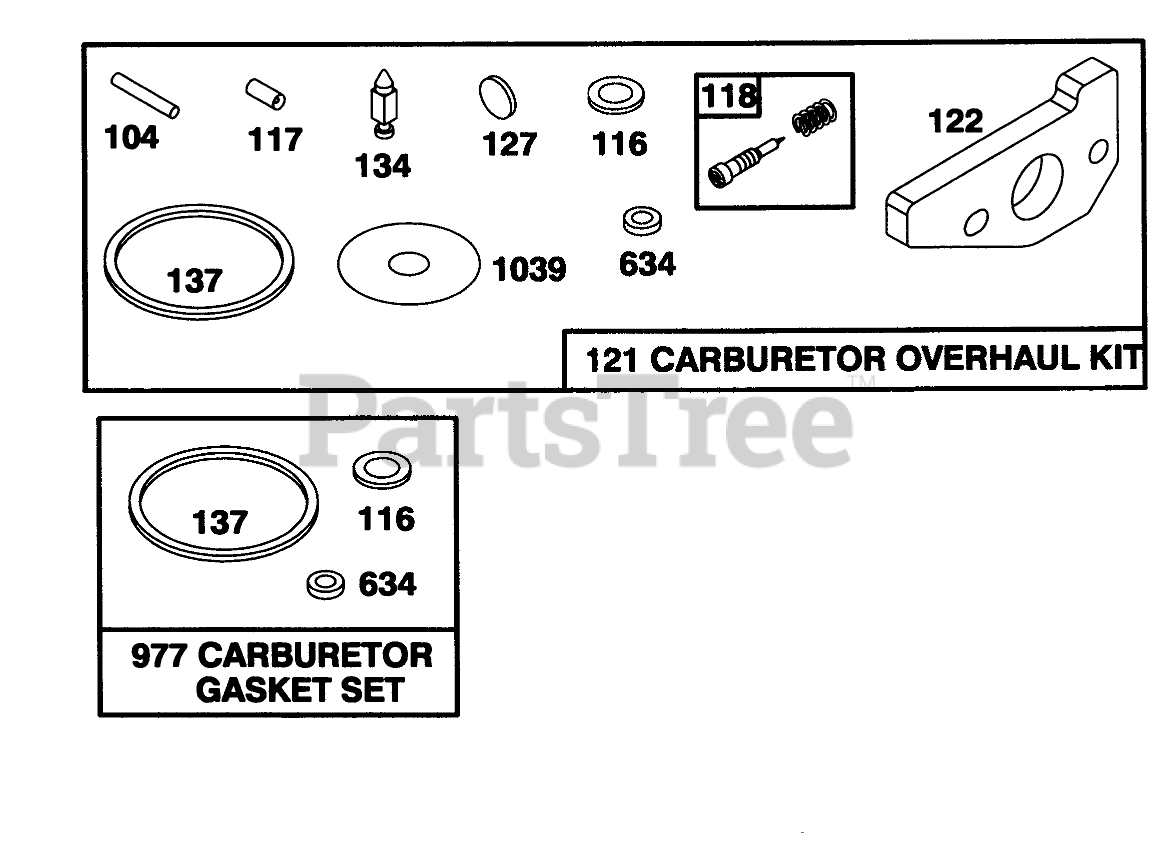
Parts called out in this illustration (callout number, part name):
104	FLOAT HINGE PIN
116	SEALING GASKET
118	VALVE KIT - NEEDLE
121	CARBURATOR OVERHAUL KIT
122	ADAPTER ASSEMBLY
134	Valve-Float (Includes Seat)
137	FLOAT BOWL GASKET
634	SEAL WASHER
977	CARBURATOR GASKET SET
1039	FLOAT LIMITER
